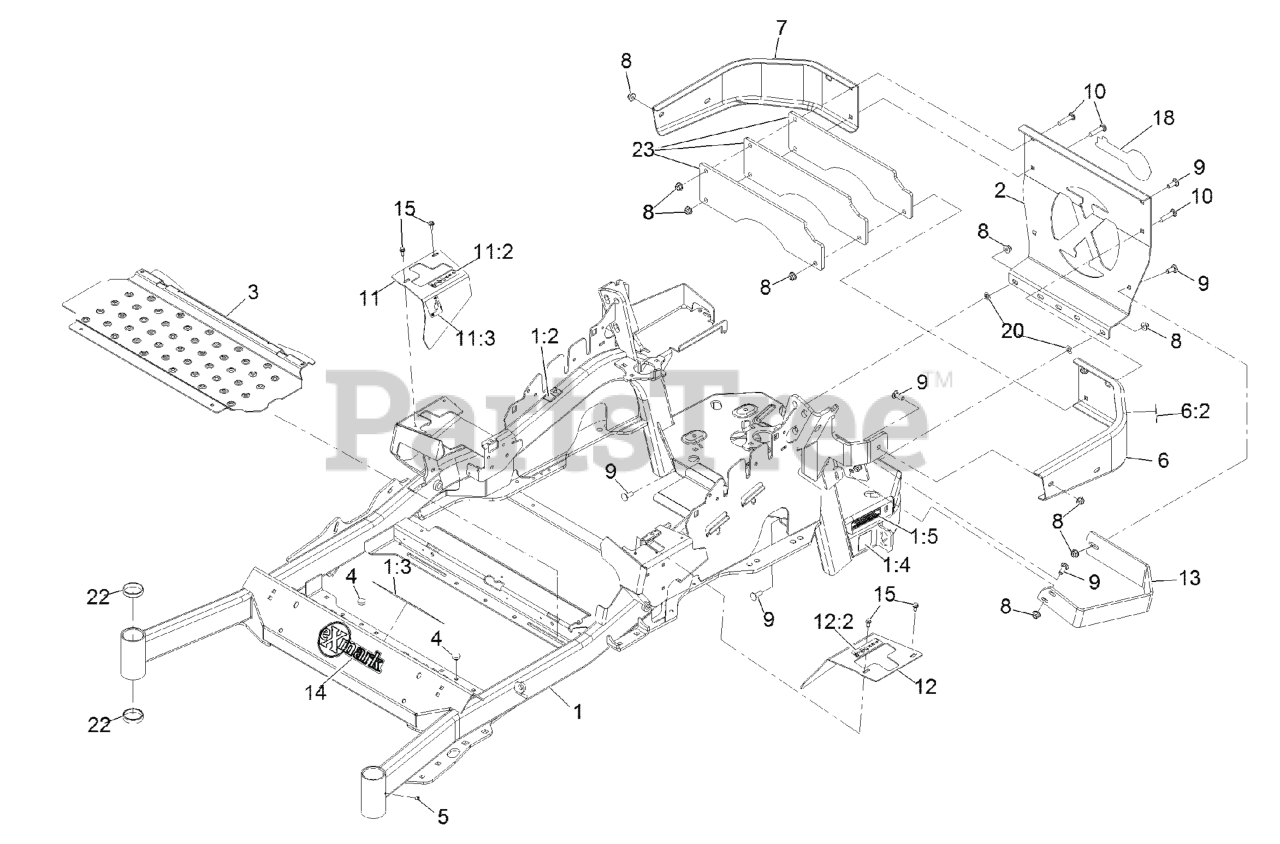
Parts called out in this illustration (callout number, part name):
1	MAINFRAME ASM
1:2	DECAL-WARNING
1:3	DECAL-DANGER
1:4	DECAL-HAZARD, PINCHED FINGER
1:5	DECAL-SPARK ARRESTER
2	PLATE,REAR GUARD
6	LH BUMPER ASM
6:2	DECAL-WARNING
7	BUMPER-RH
8	NUT-HF, NI
9	SCREW-CARR
10	SCREW-CARR
11	RH MOTION CONTROL COVER ASM
11:2	DECAL-CONTROL, MOTION
11:3	DECAL-PARK BRAKE, CE
12	LH MOTION CONTROL COVER ASM
12:2	DECAL-CONTROL, MOTION
13	GUARD-MUFFLER
14	DECAL-EXMARK LOGO
15	SCREW-HWH
18	DECAL-EXMARK LOGO
19	Decal-Patent Ttco.Com
20	NUT-PUSH
21	DECAL-FUEL FILL, CE
22	CUP-BEARING
23	PLATE-WEIGHT, 6 LB
